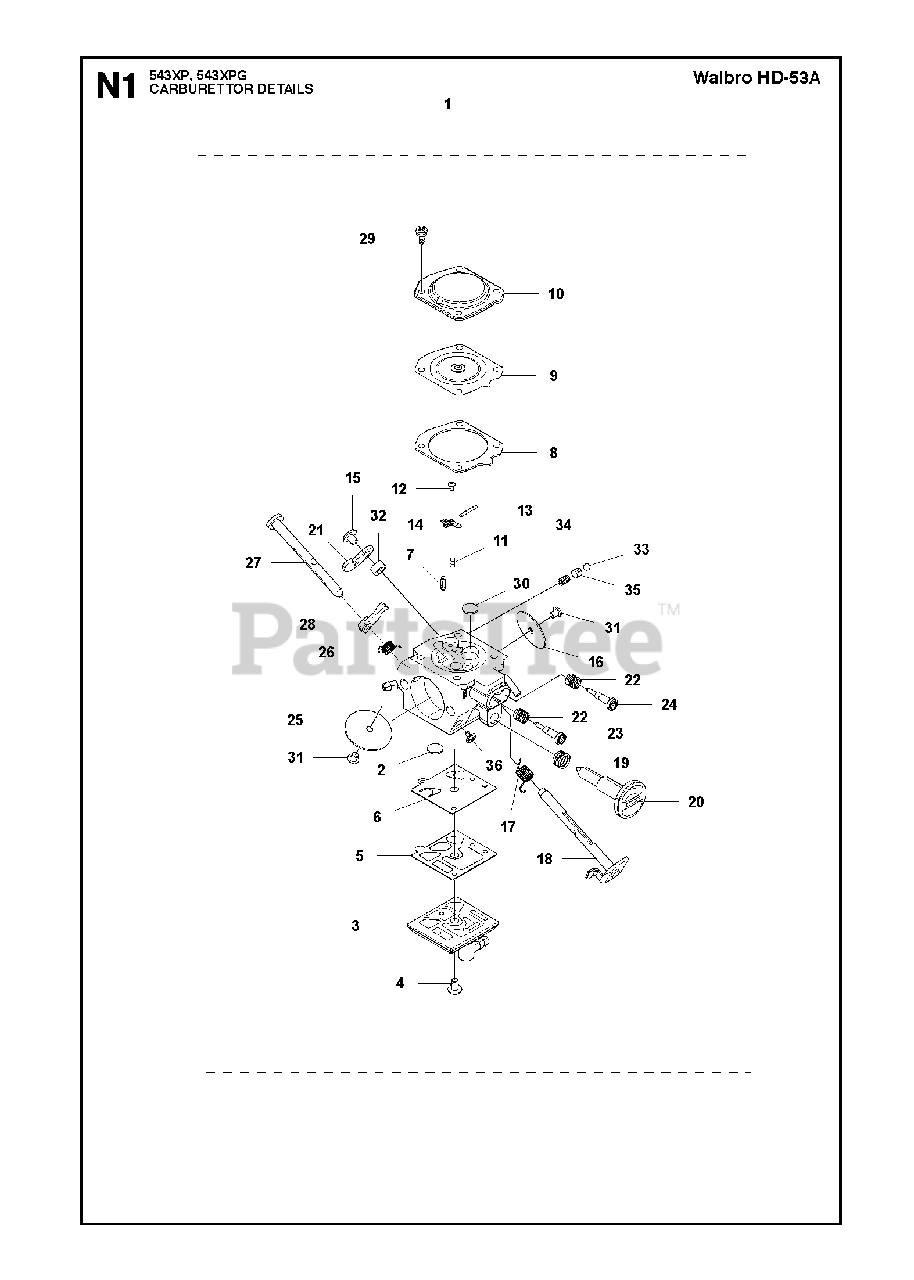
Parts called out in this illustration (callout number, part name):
1	CARBURETOR
2	SCREEN
3	COVER ASSEMBLY PUMP 21-3780
4	SCREW Z149181130
5	GASKET
6	95-75 DIAPHRAGM Z335081260
7	VALVE INLET
8	GASKET
9	DIAPHRAGM ASSEMBLY METERING 95
10	COVER METERING DIAPHRAGM 21-48
11	SPRING
12	SCREW
13	PIN
14	LEVER
15	SCREW
16	VALVE THROTTLE 34-314
17	SPRING 98-3706
18	SHAFT ASSY
19	SPRING
20	SCREW Z285082310
21	LEVER THROTTLE 18-3551
22	PIN
23	NEEDLE HIGH SPEED
24	NEEDLE IDLE
25	VALVE CHOKE 34-3504
26	SPRING 98-3718
27	SHAFT ASSY CHOKE 22-4356
28	LEVER FAST IDEL 18-3566
29	SCREW ASSY
30	PLUG
31	SCREW 96-3240
32	SPACER
33	BALL
34	SPRING
35	PISTON ASSY
36	SCREW
